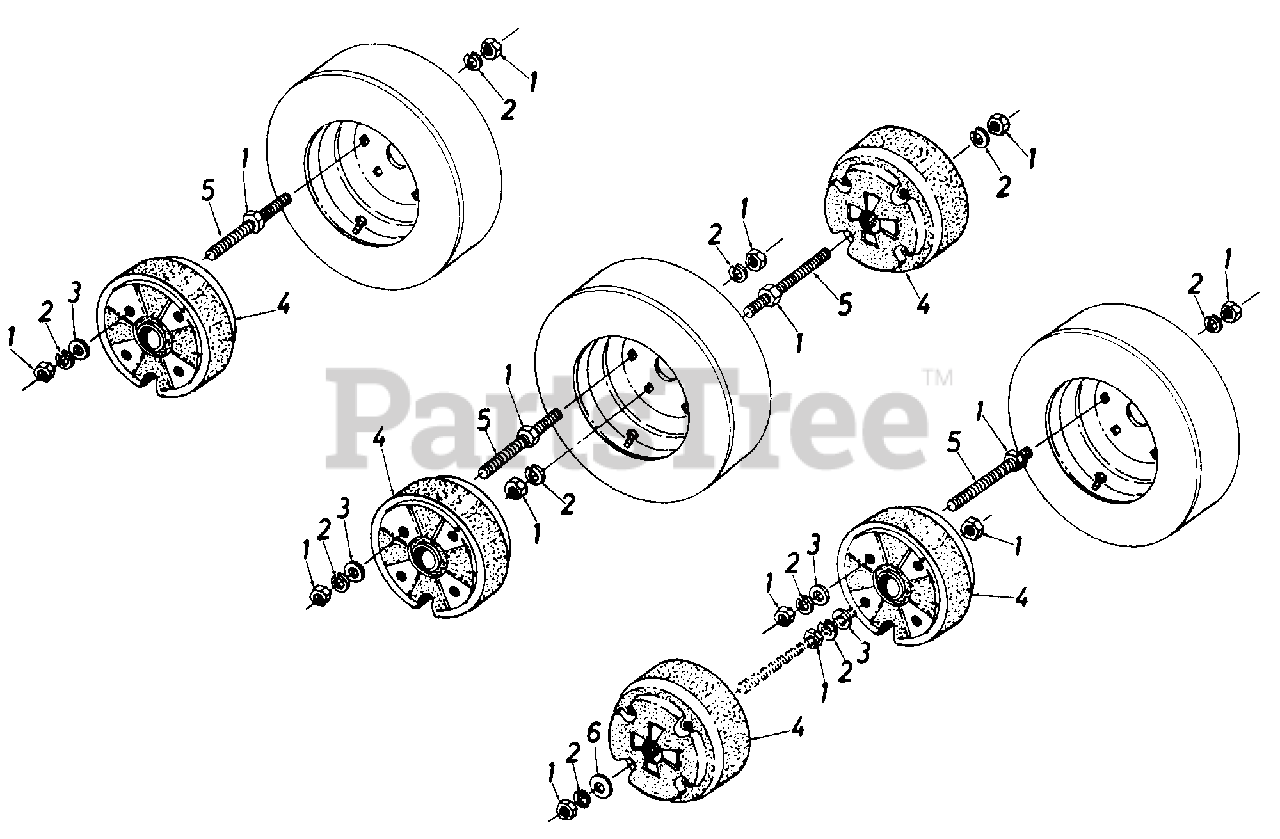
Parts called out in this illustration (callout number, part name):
1	Hex Nut 1/2-13 Thd.
2	Lock Washer 1/2" I.D.
3	FlatWasher.53" I.D. x.93" O.D.
4	Wheel Weight
5	Rod Threaded 1/2-13 x 9.50 Lg.
6	Fl.-Wash. .50" I.D. x 2.00" O. D.
